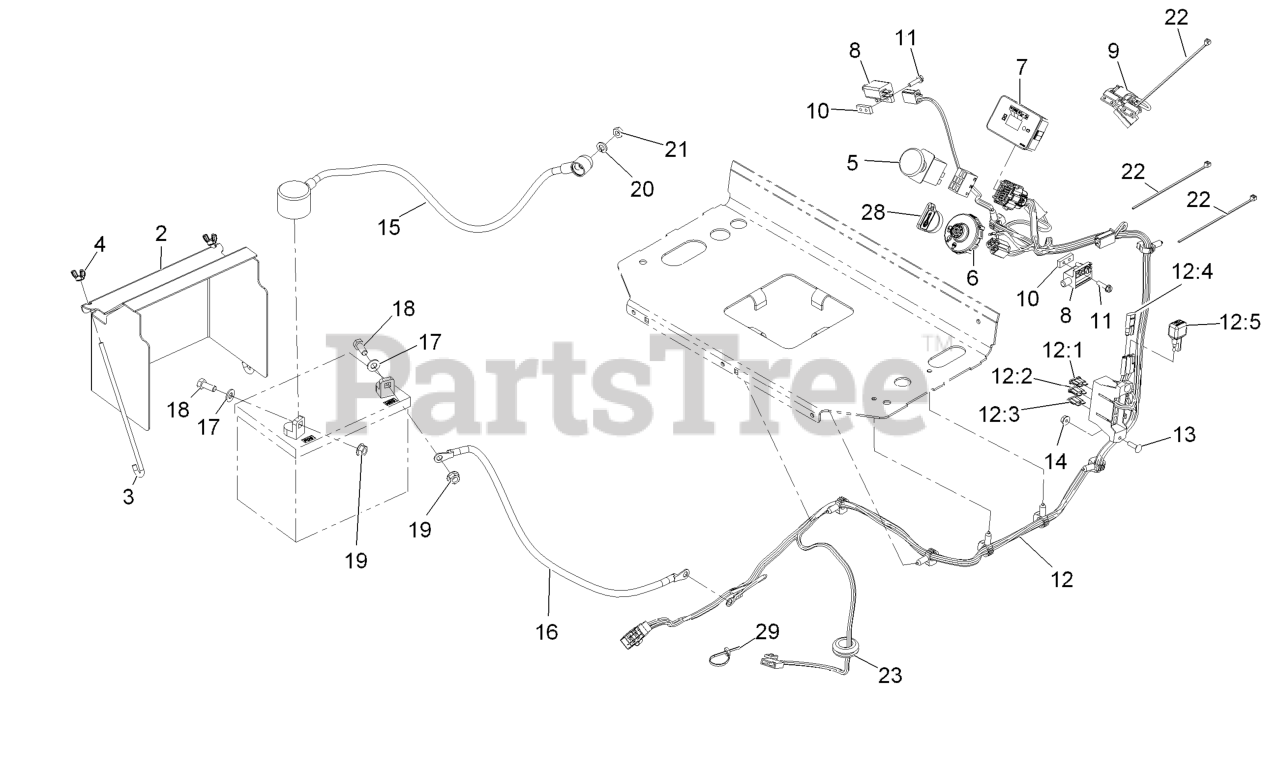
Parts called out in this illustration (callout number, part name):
2	COVER-BATTERY
3	BOLT-HOLDDOWN
4	WINGNUT
5	SWITCH-PTO, ON-ON
8	SWITCH-CLOSED, NORMALLY
9	HARNESS-SWITCH, REED
10	PLATE-TAPPED
11	SCREW-HWH
12	HARNESS-WIRE
12:1	FUSE-BLADE, 30 AMP
12:2	FUSE-BLADE, 25 AMP
12:3	FUSE-BLADE, 10 AMP
12:4	CAP-PLUG
13	SCREW-CARR
15	CABLE-BATTERY, POSITIVE
16	CABLE-BATTERY, BLACK
17	WASHER-PLAIN
18	SCREW-HH
19	NUT-HHF, SMOOTH
20	SCREW-HH
21	NUT-HEX
22	TIE-CABLE
23	GROMMET
28	KEY-IGNITION
29	TIE-CABLE
